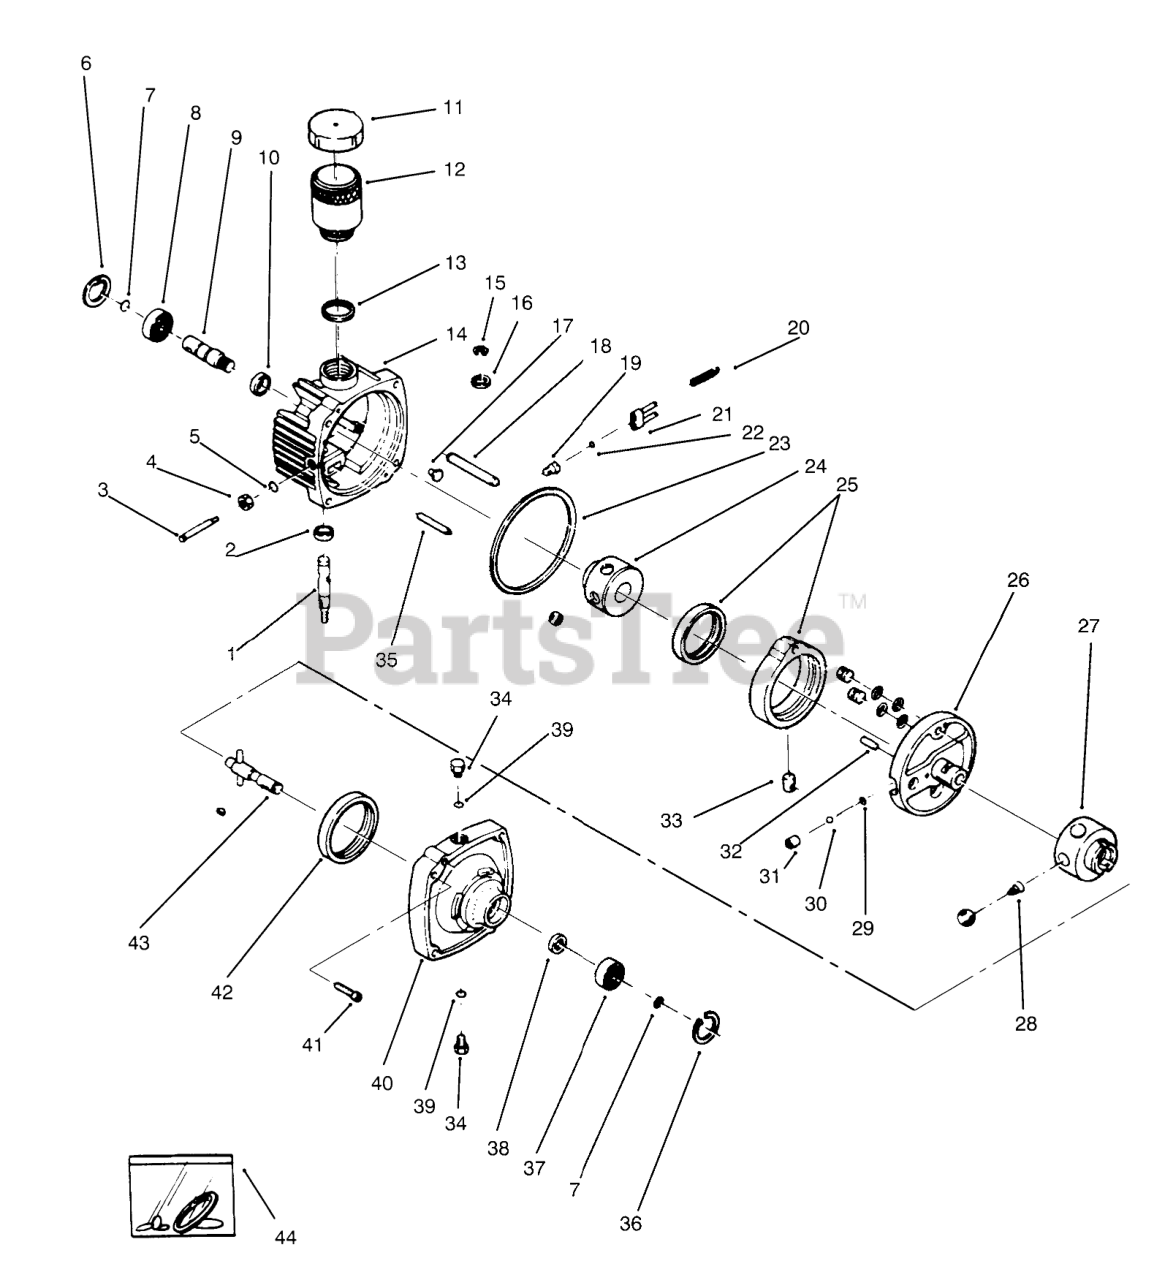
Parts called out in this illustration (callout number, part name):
1	KIT-CONTROL SHAFT
2	SEAL-OIL
3	SHAFT-DUMP VALVE
4	Nut
5	O-RING
7	SNAP-RING
8	BEARING-BALL (INPUT)
9	SHAFT-INPUT
10	SEAL-OIL
11	RESERVOIR COVER
12	BODY-RESERVOIR
13	SEAL-RING SQUARE CUT
14	Kit-Cover (Incl. Ref. # 1,2,10,15.16,18&35)
15	RETAINING-RING
16	Washer-Control Shaft
17	Button
18	Dowel (Ref.)
19	SUB-ASS'Y O-RING
20	SPRING-VALVE
21	SUB-ASS'Y BRACKET
22	O-RING
23	SEAL-RING SQUARE CUT
24	SUB-ASS'Y PUMP ROTOR
25	Ring Sub-Assembly-Cam (Incl. Pump Race & Cam Ring)
26	Pintle Assembly-Used in CCW rotation trans. Model #00700-023 (Incl. Ref.#29-32)
27	SUB-ASS'Y MOTOR
28	SPRING-PISTON
29	Ring-Retaining
30	Ball
31	BODY-CHECK VALVE
32	Pin-Coil
33	INSERT-CAM RING
34	Plug Assembly-O-Ring (Incl. Ref. #39)
35	Dowel (Ref.)
37	Bearing-Ball
39	O-Ring
40	Body Assembly (Incl. Ref.# 7,34,36-39,41 & 43)
41	Screw
42	Seal-Oil
43	SUB-ASS'Y OUTPUT
44	Kit-Overhaul Sealing (Incl. 112632 Gasket Ass-y & Ref. #2,4,5,10,13,19,22,23,&39)
